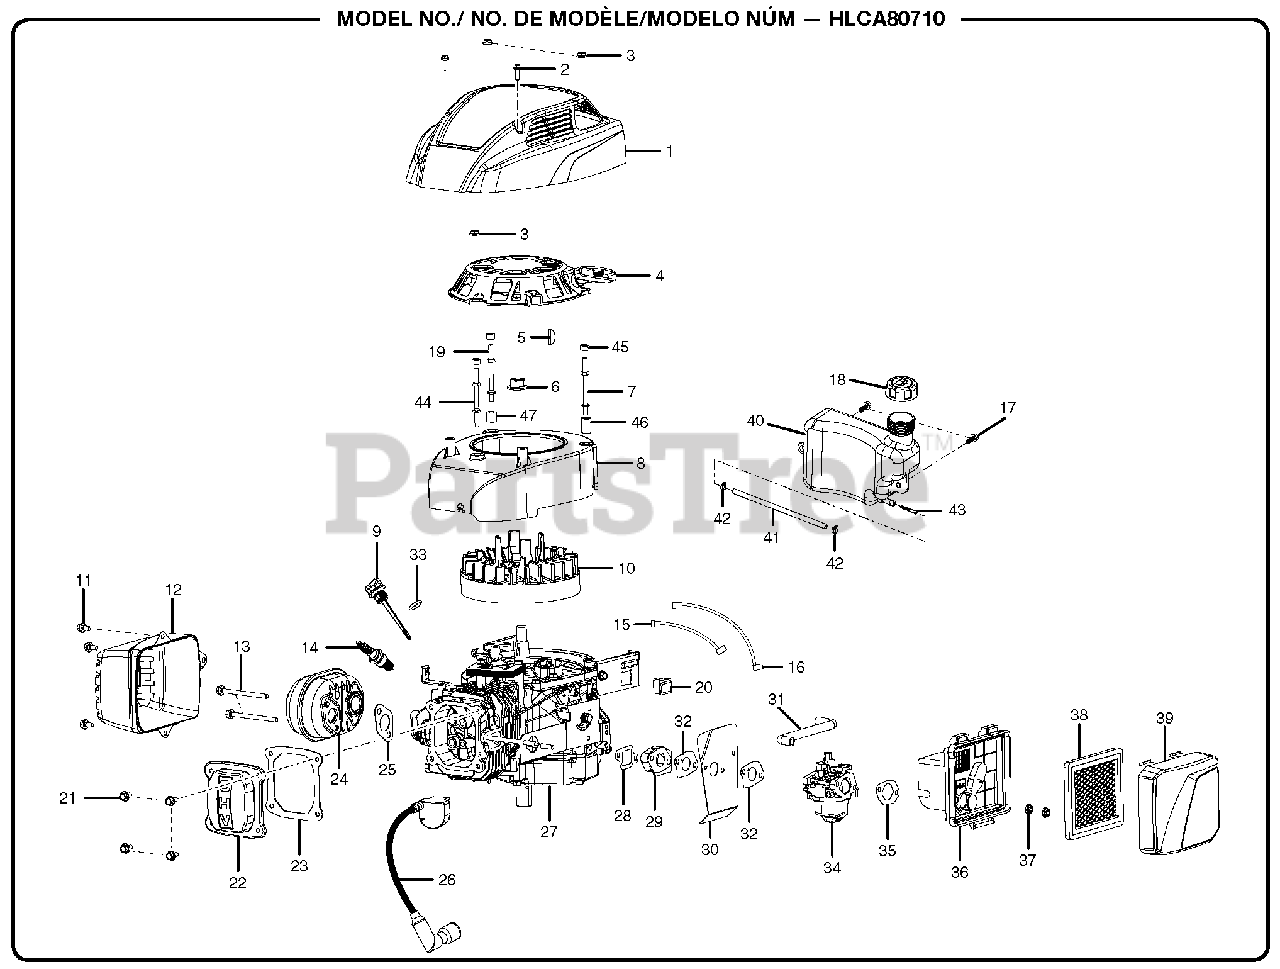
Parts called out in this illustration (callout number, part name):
1	Engine Cover
2	Bolt (Engine Cover)
3	Hex Nut (Starter)
4	Starter w/Recoil Assembly
6	Flywheel Nut
8	Engine Shroud
9	Oil Dip Stick Assembly
10	Flywheel Assembly
11	Bolt (Muffler Cover)
12	Muffler Cover
13	Muffler Bolt
15	Ground Wire
17	Bolt (Fuel Tank)
21	Bolt (Valve Cover)
22	Valve Cover
23	Valve Cover Gasket
25	Muffler Gasket
26	Ignition Coil
27	Crankcase Assembly
28	Gasket (Insulator Plate)
29	Insulator Plate
30	Gasket (Insulator Plate)
31	Breather Tube
32	Gasket (Carburateur)
33	Seal Ring
34	Carburateur Assembly
35	Gasket (Air Filter)
36	Air Filter Case
37	Hex Nut (Air Filter)
39	Air Filter Cover
42	Clamp (Fuel Tube)
43	Fuel Filter
45	Bushing (Engine Shroud)
46	Bushing (Tall)
47	Bushing (Short)
